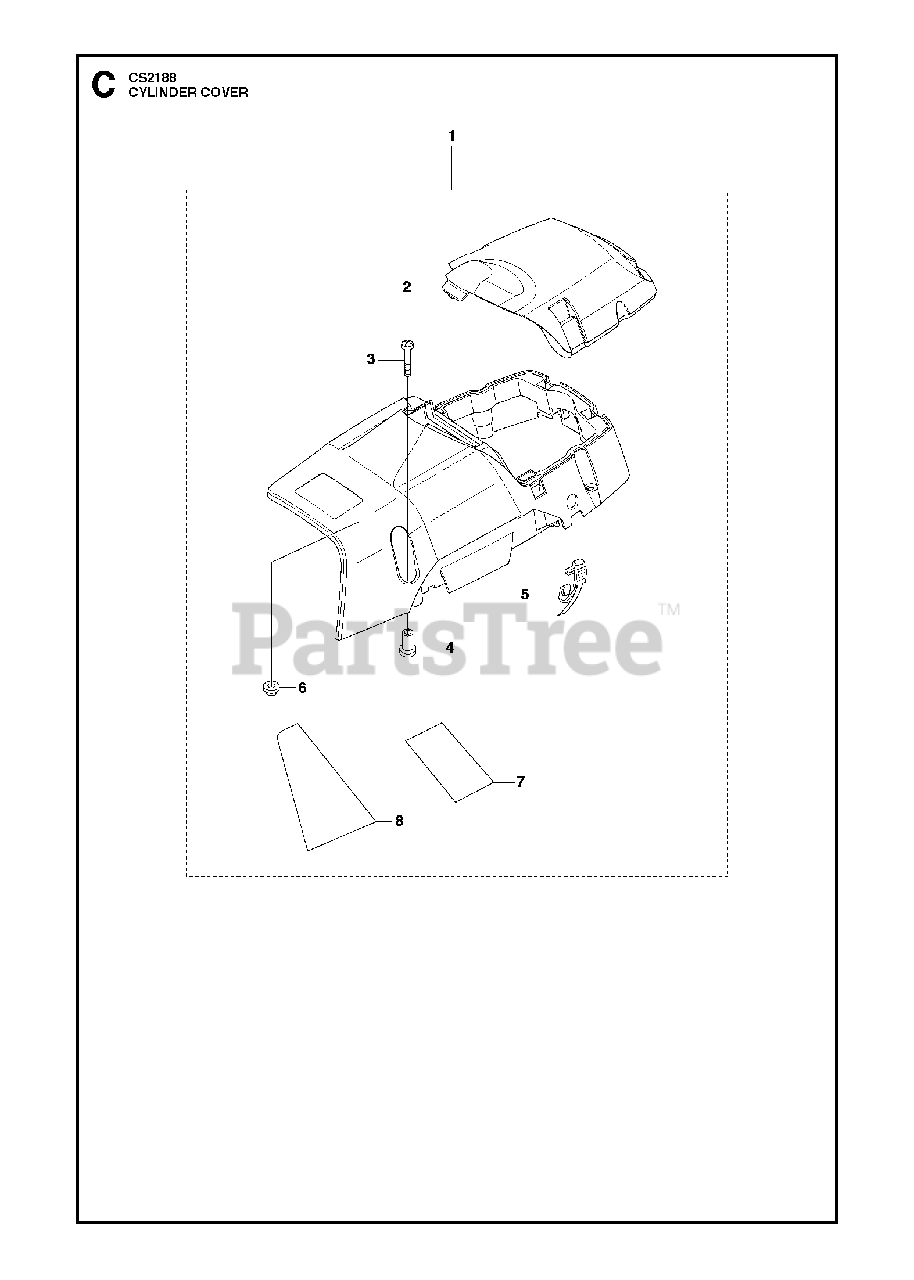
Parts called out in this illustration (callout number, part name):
1	CYLINDER COVER
2	COVER
3	SCREW
4	SLEEVE
5	CLIP
6	GROMMET
